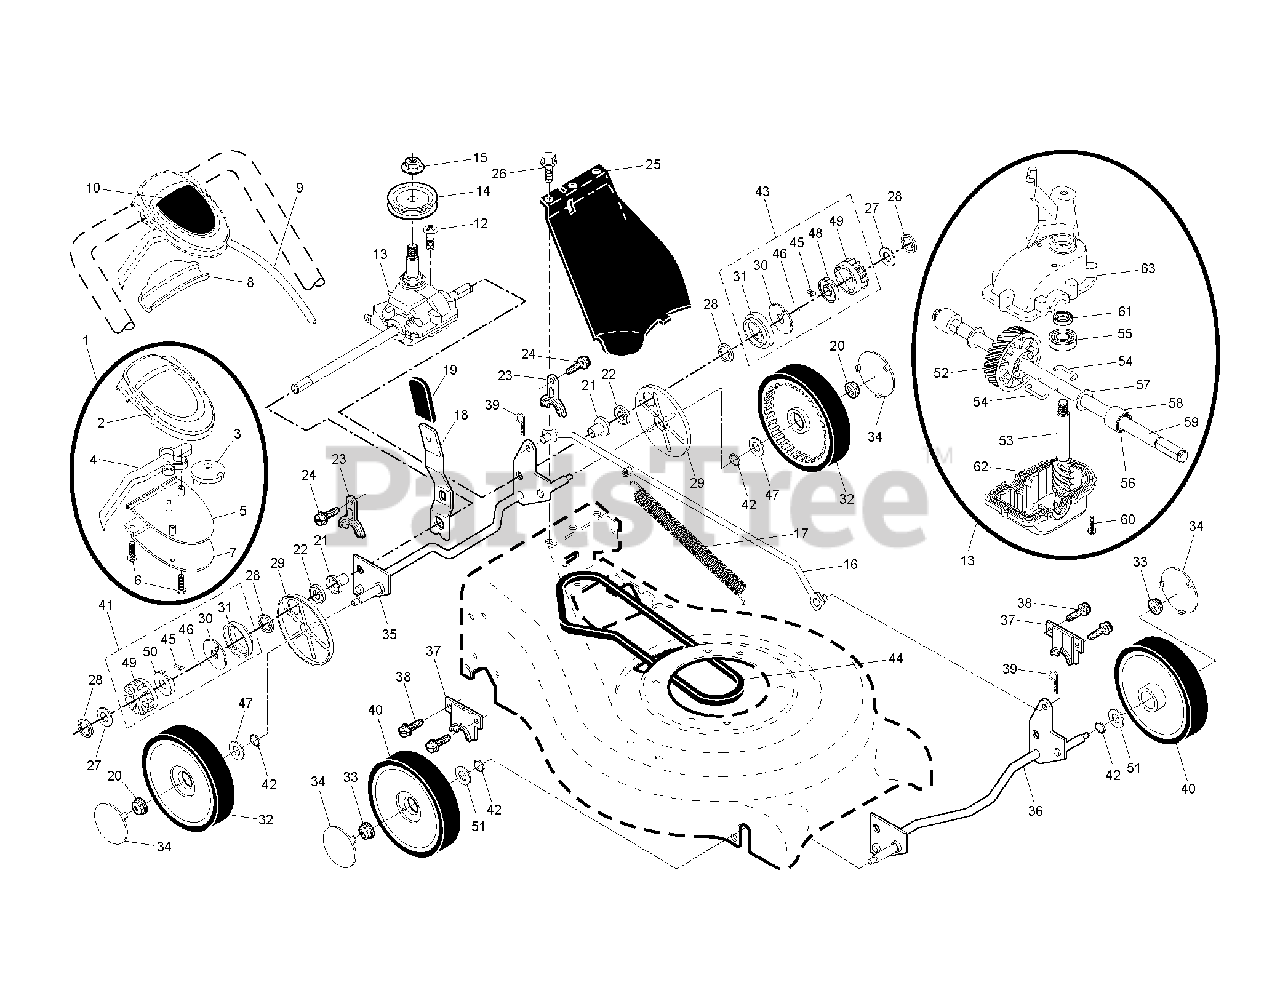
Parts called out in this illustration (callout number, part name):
3	PULLEY, DRIVE CONTROL
6	SCREW, PHILLIPS HEAD 10 X 5/8
7	BRACKET.DRIVE.CONTROL.MOUNT
8	EA WLK COVER PLATE.BLK
9	DRIVE CONTROL CABLE
13	TRANSMISSION.21.RWGD
15	FLANGED LOCKNUT 3/8-16 ZINC
16	ROD CONNECTING
17	SPRING
18	SPRING.SELECTOR.SPT.21
19	KNOB, SELECTOR SPRING
20	HEX FLANGE LOCKNT
21	RP BEARING SUPPORT
22	BEARING, BALL
23	BRACKET
27	WASHER
28	E-RING 7/16 RE
29	COVER.DUST.WHEEL
30	DISC.DRIVE.21.EZ-WALK
31	SEAL.PINION
32	WHEEL, 9 X 2
33	HEX FLANGE LOCKNT
34	HUBCAP
35	SHAFT.ASM.REAR.TORQUE
36	SHAFT ASSY FRONT
37	RETAINER.FRONT.SHAFT
39	RETAINER CLIP
40	WHEEL ASMBLY FRONT
41	PINION ASSY, RH
42	O-RING
43	PINION ASSY, LH
44	V-BELT
45	PAWL.DRIVE.21.EZ-WALK
46	SPRING, TORSION
47	WASHER FLUT
48	RETAINER.DRIVE.21.EZ-WALK.LT
49	GEAR, PINION
50	RETAINER, DRIVE, RH
51	WASHER PM
52	GEAR.24.TOOTH.WALK.MOWER
53	SHAFT INPUT
54	WIRE, FORMED
56	SEAL.OUTPUT.SHAFT
59	SHAFT.OUTPUT.RGD.VS/EZ
61	SEAL INPUT SHAFT
62	CASE, LOWER
63	CASE, UPPER
